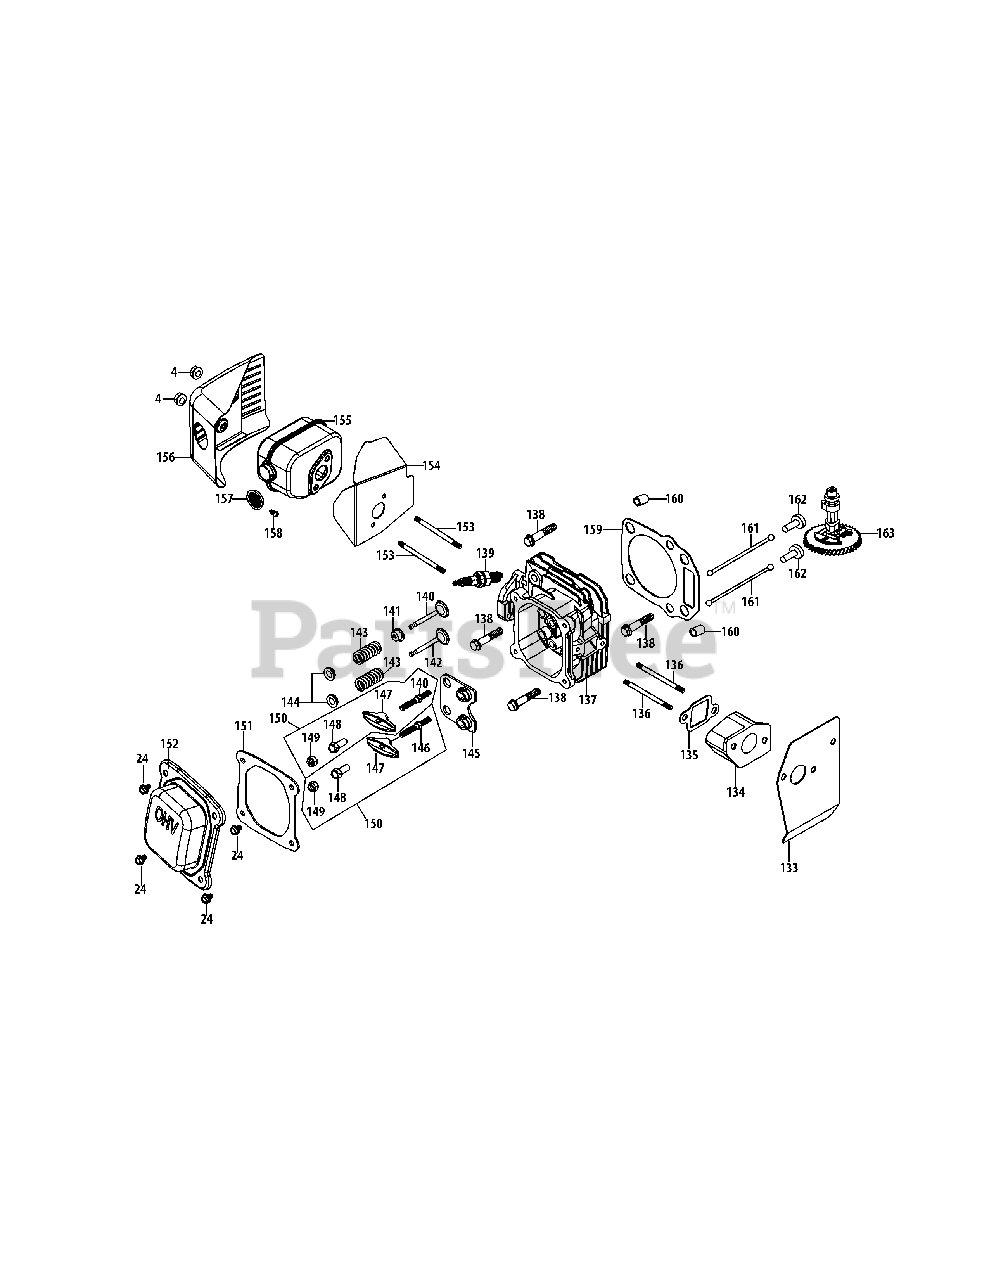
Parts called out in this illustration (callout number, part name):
4	Nut M6 X 10 Mm
24	Bolt M6×14
133	Carburetor Gasket
134	Carburetor Insulator
135	Carburetor Insulator Gasket
136	Stud M6×113
137	Cylinder Head Assembly
138	Head Bolt M8×54
139	Spark Plug
141	Intake Valve Seal
143	Valve Spring
144	Valve Spring Retainer
145	Push Rod Guide
146	Rocker Arm Stud
147	Rocker Arm
148	Valve Adjusting Nut
149	Pivot Locking Nut
150	Rocker Arm Assembly
151	Valve Cover Gasket
152	Valve Cover
153	Stud M6×95
153	Muffler Stud Assemlby
154	Muffler Gasket
155	Muffler Assembly
156	Muffler Shield
157	Spark Arrestor
158	Self-Tapping Screw M3.5×9.5
159	Cylinder Head Gasket
160	Dowel Pin 10×16
161	Push Rod Kit
163	Camshaft Assembly
